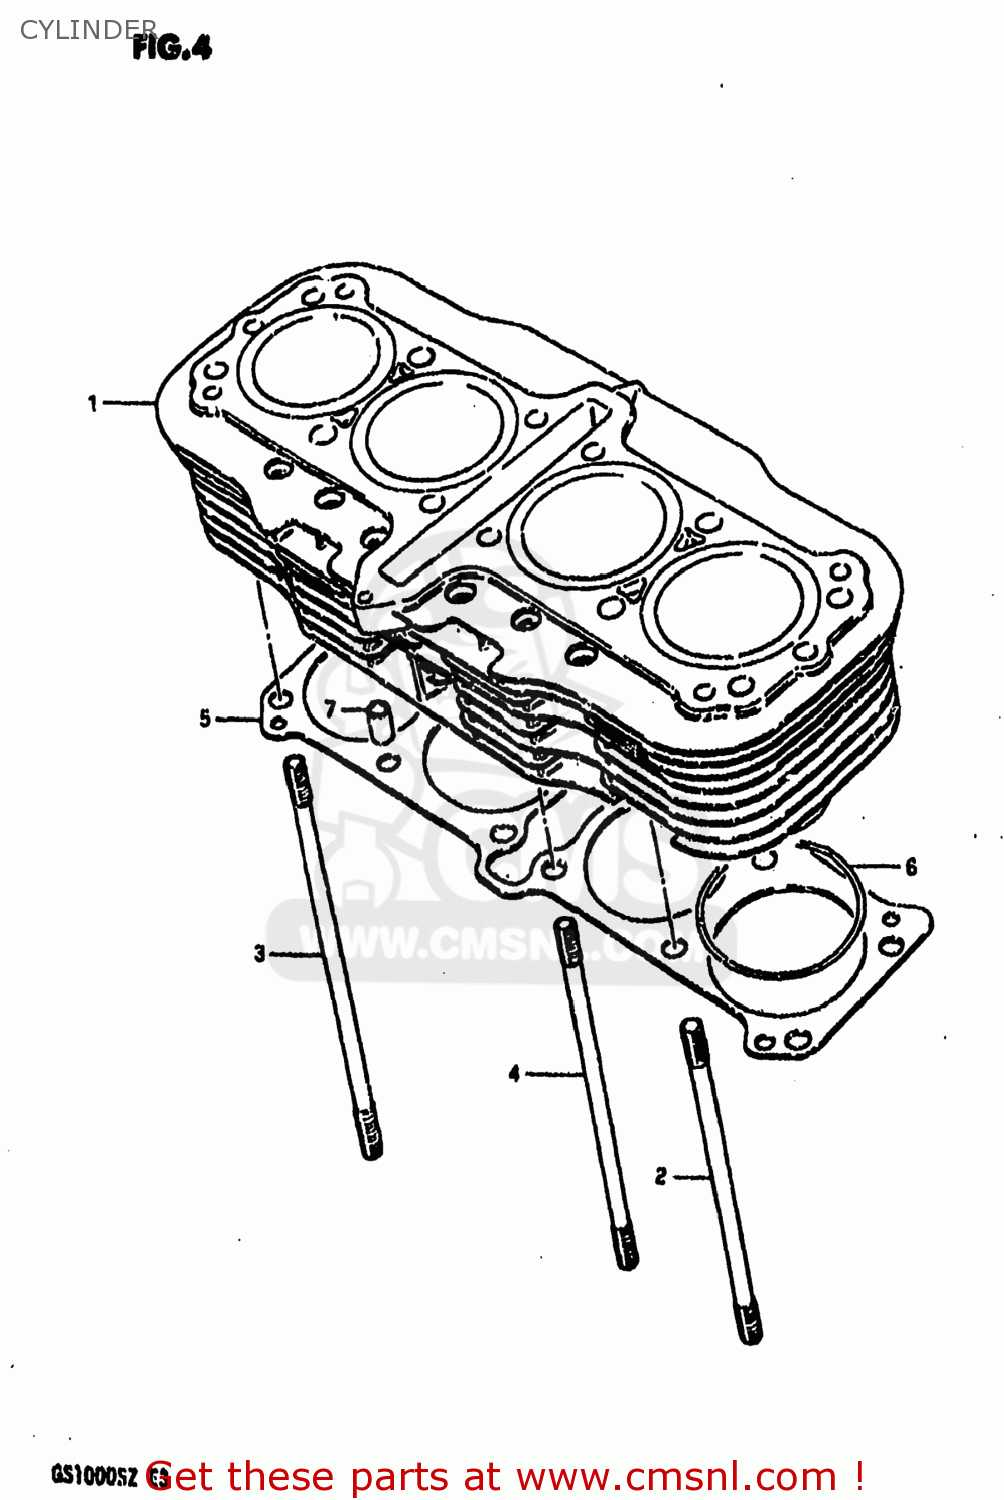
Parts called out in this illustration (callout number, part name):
1	CYLINDER
2	BOLT,STUD
3	STUD
4	BOLT,STUD
5	GASKET (MCA)
6	O RING(D:2,ID:74)
7	PIN
